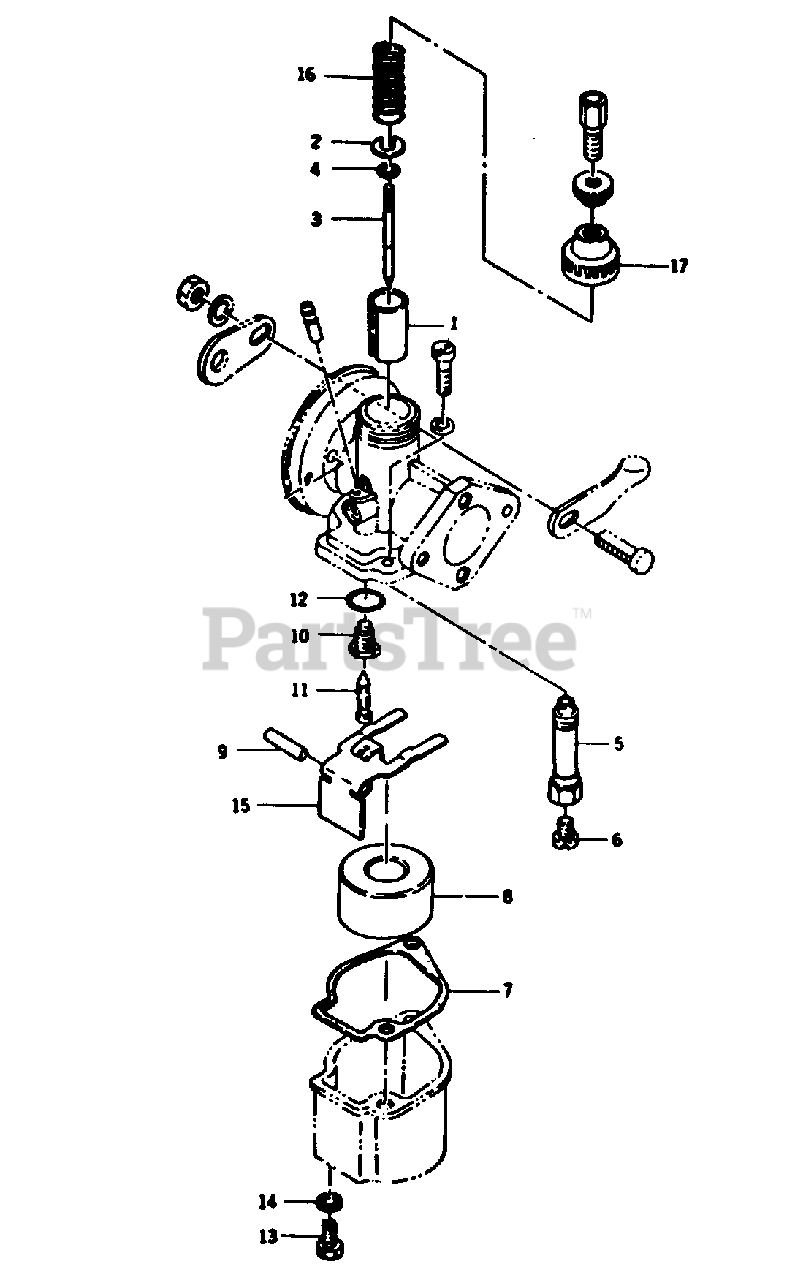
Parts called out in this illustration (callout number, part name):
1	Valve, Throttle
3	Jet, Needle
4	Clip, Needle
5	Jet, Needle
6	Jet, Main 80
9	Pin, Float
10	Seat, Needle
11	Valve, Needle
13	Screw, Drain
15	Hinge, Float
16	Spring, Throttle
17	Cap, Body
